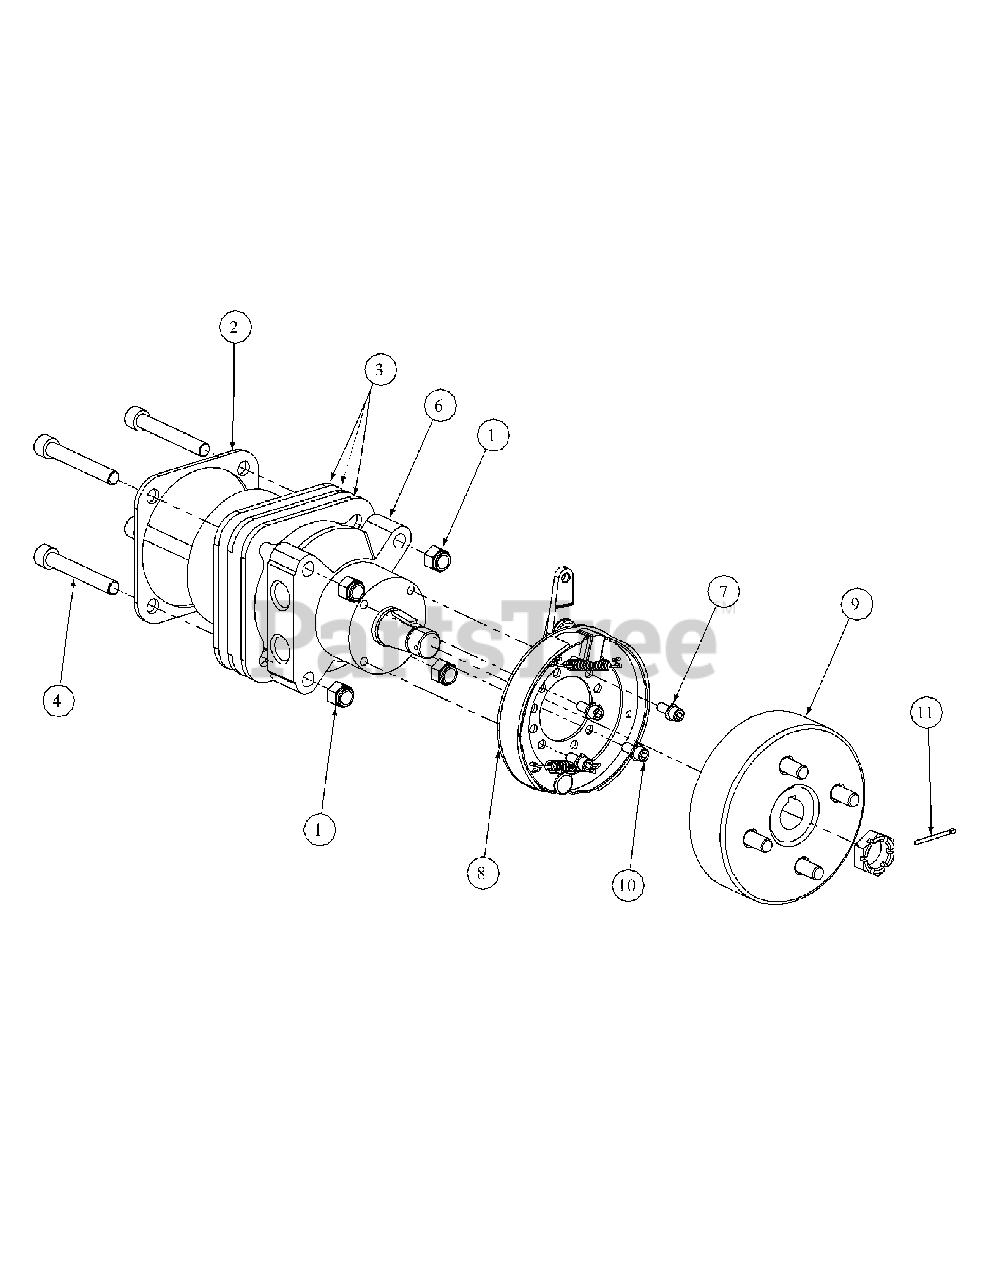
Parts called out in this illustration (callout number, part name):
1	Lock Nut, Nylon Insert, 1/2-13
2	Motor Plate
3	Motor Spacer
4	Socket Head Capscrew, 1/2-13; 3-1/2
4	Capscrew, 1/2-13 x 3.5
5	Hyd. Motor, Parker Left Hand
6	Hydro Motor, Parker Right Hand
7	Lock Washer, 5/16
8	Brake Assembly w/Line
9	Hub and Drum Assembly w/Studs
10	Capscrew w/Socket, 5/16-18 x 3/4
11	Cotter Pin 1/8 x 1-1/2
